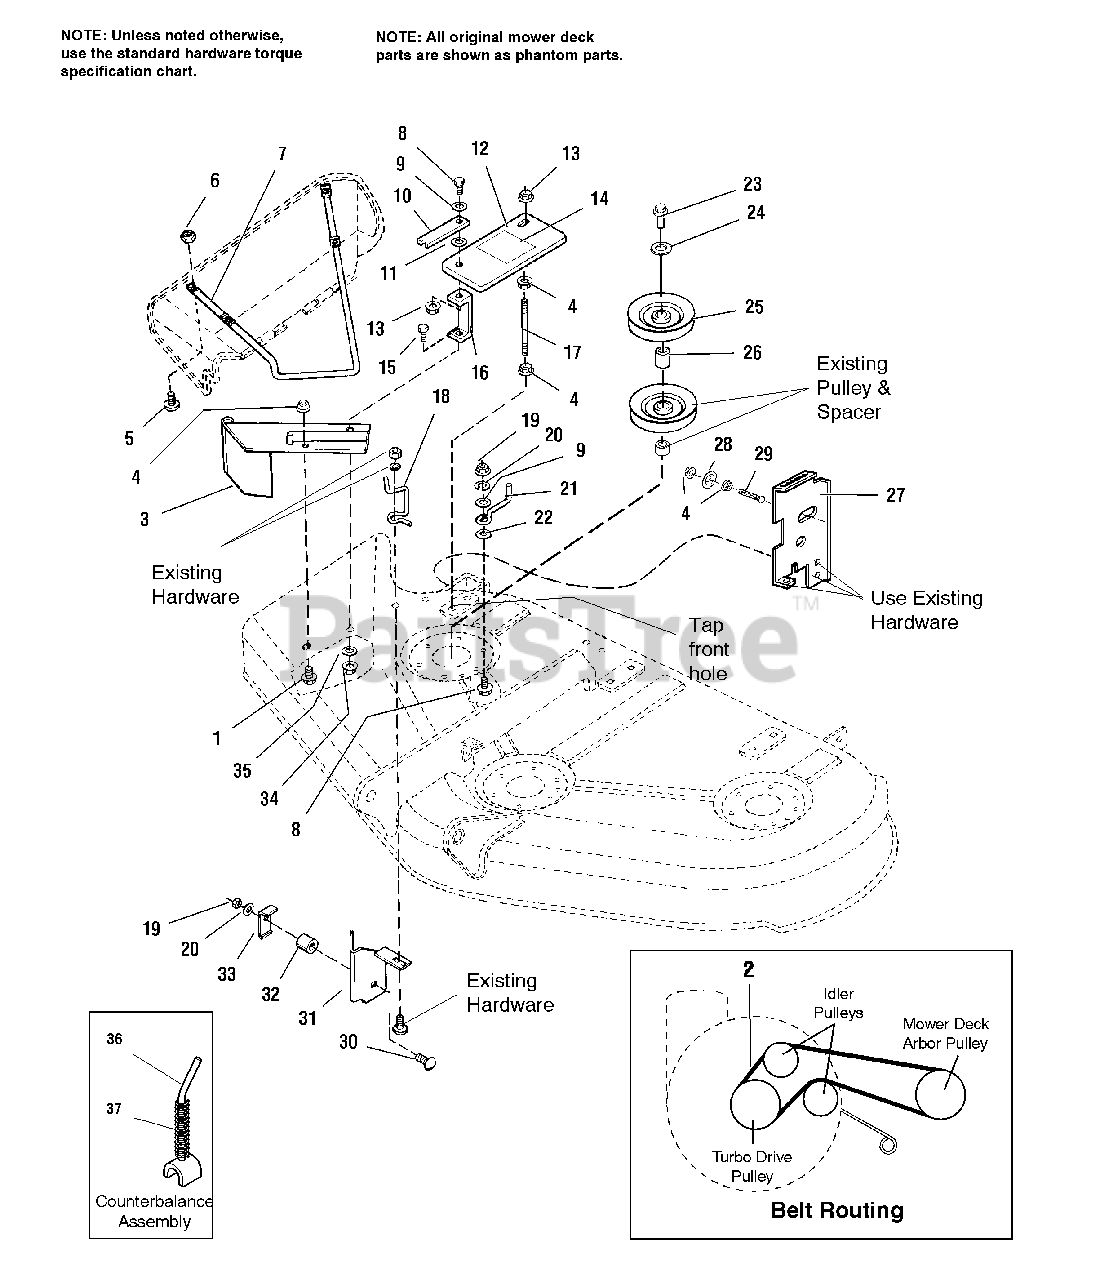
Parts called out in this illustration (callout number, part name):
1	CARRIAGE BOLT, 5/16-18 x 3/4" Lg.
3	PIVOT ASSEMBLY
4	NUT, Hex Flange, WhizOlock, 5/16-18
5	CAPSCREW, Truss Head, #10-24 x 3/4" Lg.
6	NUT, Nylock, #10-24
7	ROD, Deflector
8	CAPSCREW, Hex Hd., 5/16-18 x 1" Lg.
9	WASHER, Flat, 11/32
10	SUPPORT STRAP, Deflector
11	WASHER, Nylon, 0.388" Dia.
12	COVER, Turbo Belt
13	NUT, Hex, Nylock, 5/16-18
14	DECAL, Warning
15	CAPSCREW, Hex Hd., 5/16-18 x 1" Lg.
16	SUPPORT, Belt Cover
17	STUD, 5/16-18 x 5-3/4" Lg.
18	LATCH, Spring Wire
19	NUT, Hex, 5/16-18
20	LOCKWASHER, 5/16
22	WASHER, Flat, 3/8
23	NUT, Sleeve
24	WASHER, Belleville
26	HUB, Double, 1.160" Long
27	BRACKET, Height Adjustment
29	CAPSCREW, Rnd Hd., 5/16-18 x 2.5 Lg.
30	CARRIAGE BOLT, 5/16-18 x 1-1/4" Lg.
31	BRACKET ASSEMBLY
33	BRACKET, "L"
34	NUT, Hex Flange, Whiz-Lock, 5/16-18
35	WASHER, Flat, 13/32
36	LEVER ASSEMBLY, ZT Counterbalance
37	SPRING, Compression
